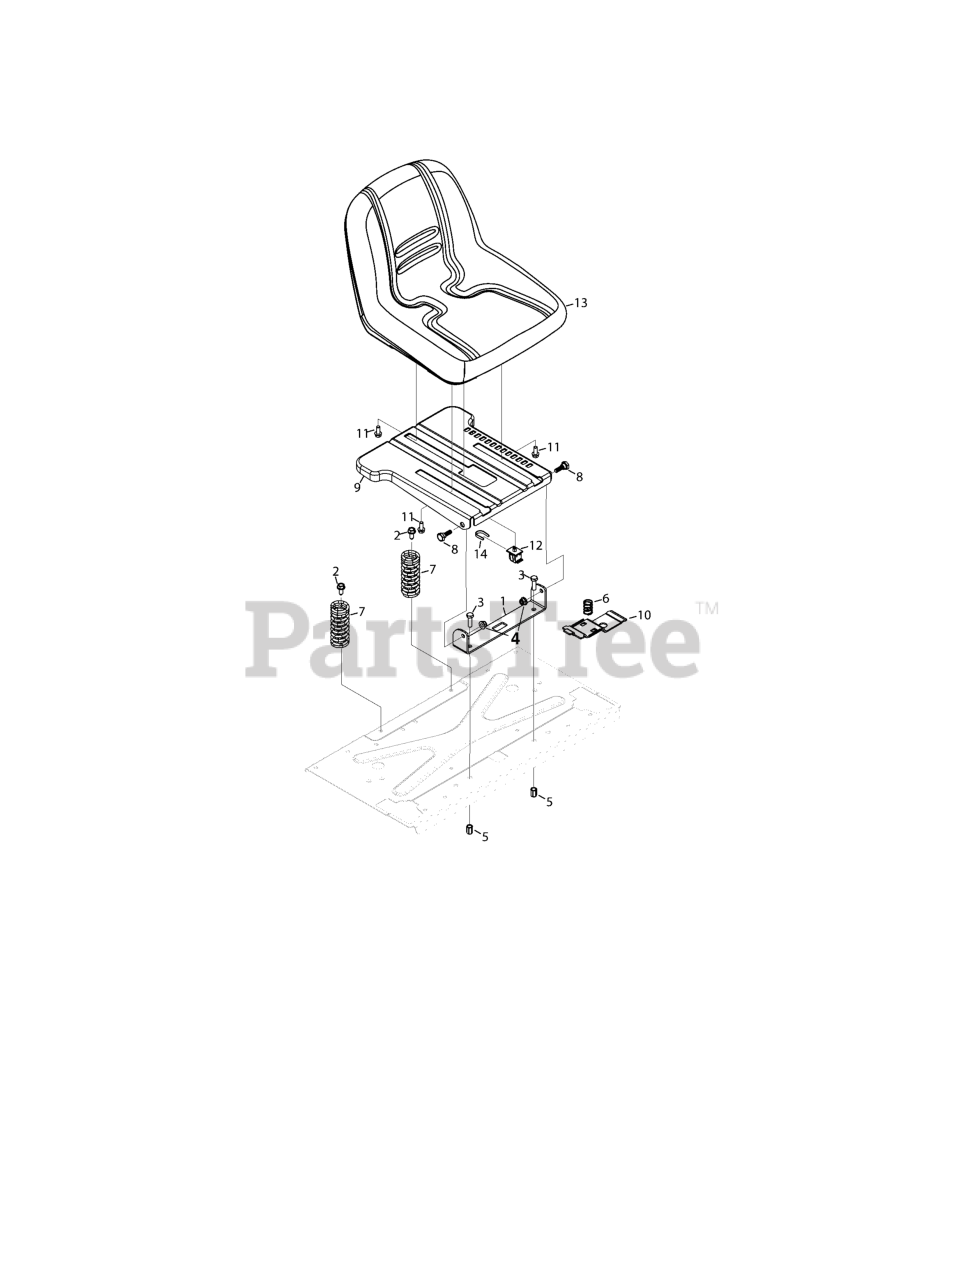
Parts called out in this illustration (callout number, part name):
1	BRACKET, Seat Pivot
2	SCREW, 5/16-18 X .750, Hex Washer
3	SCREW, 5/16-18 X 1.00 GR5
4	NUT, Lock
5	NUT, Rivet,  5/16-18
6	SPRING, Compression
7	SPRING, Compression
8	SCREW, .437, Shoulder
9	BRACKET, Seat Mounting
10	LEVER, Seat Adjust
11	SCREW, 3/8-16 X .875 GR5
12	SWITCH, Seat
13	SEAT, High Back
14	CLIP, Retaining
